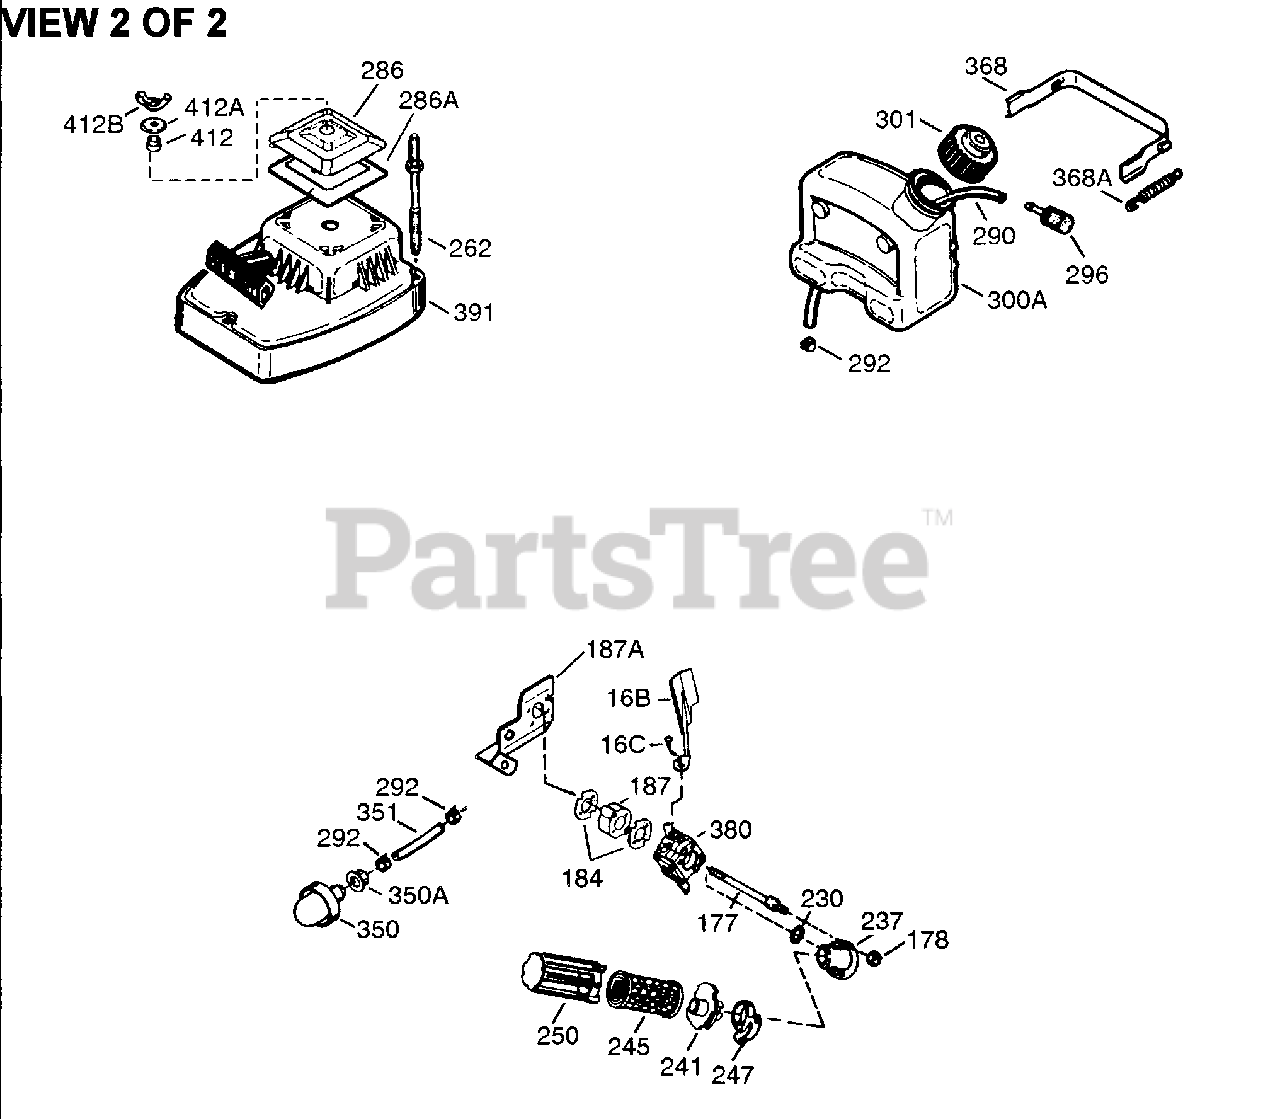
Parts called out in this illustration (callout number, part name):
16B	Air Vane
16C	Screw, Torx T-8, 3-48 x 7/32"
177	Carburetor Mounting Stud
178	Lock Nut, 10-24
184	Carburetor Gasket
187A	Air Baffle (Incl. 184 & 187)
230	"O" Ring
245	Air Filter (Poly) (also available in Packaged Part #740097 (incl. 450255 & 450257))
250	Air Cleaner Cover
290	Fuel Line
292	Fuel Line Clamp
301	Fuel Cap
380	Carburetor (Incl. 184)
391	Rewind Starter & Housing Ass'y.
